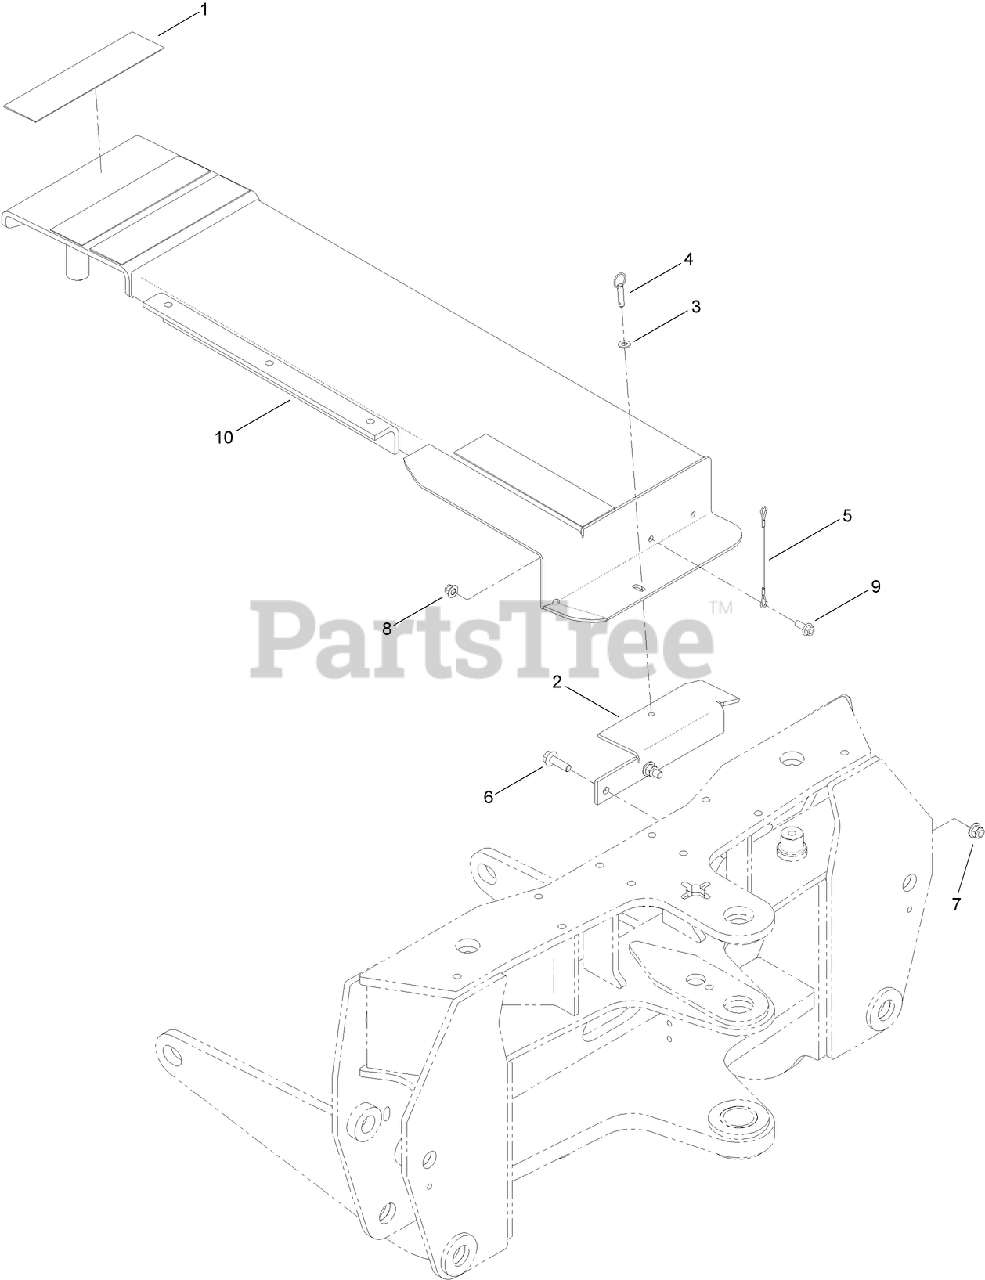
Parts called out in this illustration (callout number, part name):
1	TAPE-ANTI SKID, CATWALK
2	ANGLE-SUPPORT, WALKWAY
3	WASHER-FLAT
4	PIN-Cotterless
5	RETAINER-ROPE, WIRE
7	NUT-HHF, LOCK
8	NUT-FLANGE, NYLOCK
9	SCREW-FLANGE
